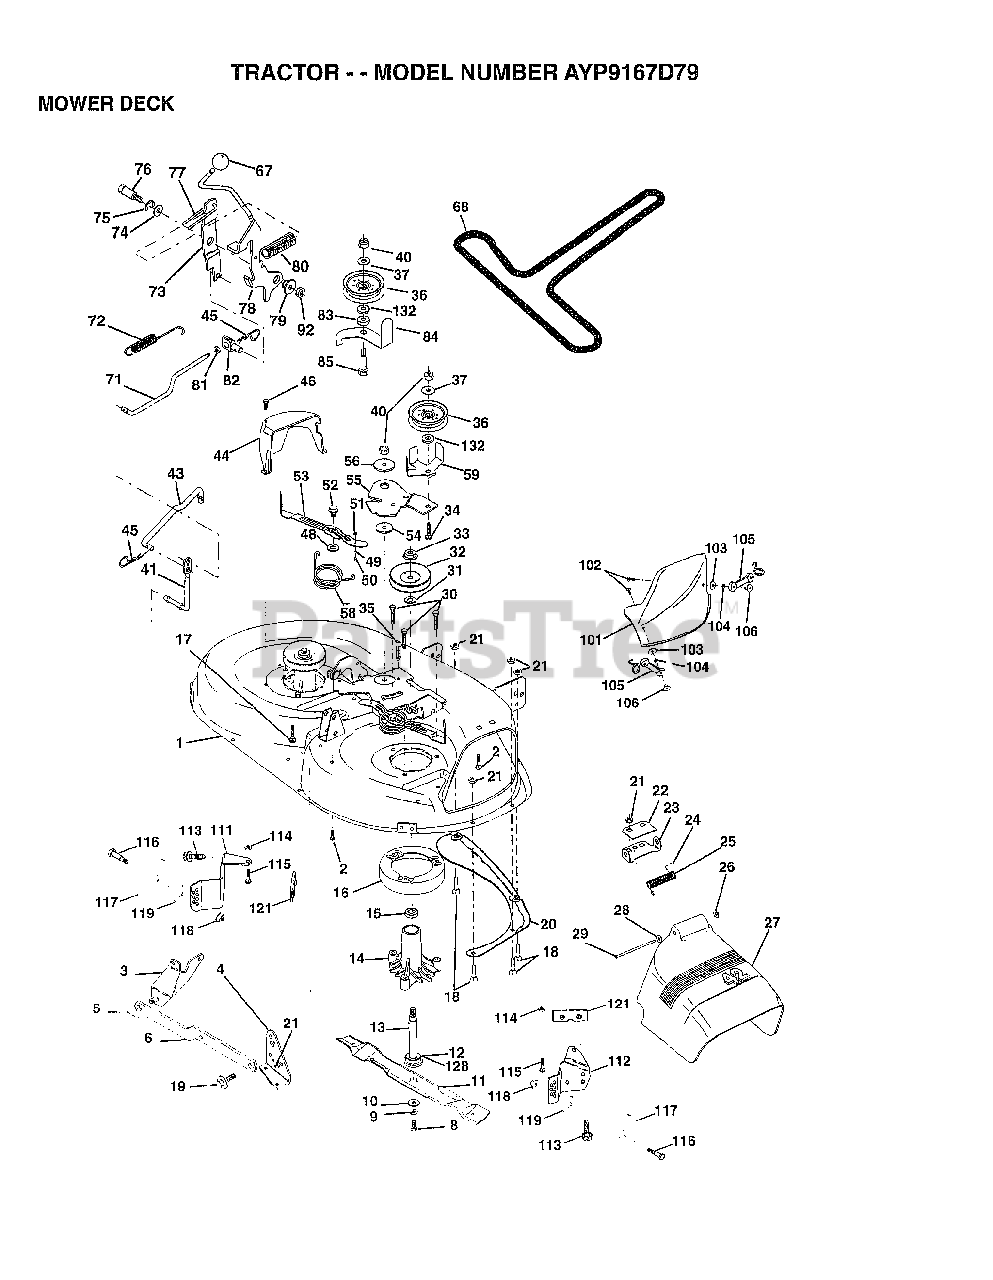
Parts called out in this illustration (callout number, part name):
1	DECK.WELD.42.
2	BOLT
3	BRKT ASM SWAY BAR
4	BRKT DECK SW BAR
8	BLADE BOLT
10	WASHER.HARD.BLADE
11	"BLADE.42"" MULCHER"
12	BEARING.BALL
14	HSG ASM MANDREL
15	BEARING
16	STRIPPER RND MWR
17	BOLT RDHD 3/8-16
18	BOLT
19	BOLT SHD 5/16-18
22	STIFFENER BRKT
23	DEFLECTOR BRKT
24	CAP-SLEEVE LT
25	SPRING TORSION
27	DEFLECTOR.SHIELD
28	WASHER
29	HINGE ROD
30	"SCREW-THD ROLL,WA"
31	WASHER
32	PULLEY.MANDREL.42
34	BOLT
35	XMAS TREE FASTNER
36	FLAT IDLER PULLEY
37	WASHER
41	PIVOT ROD
43	ROD CLUTCH W/NIBS
44	GUARD MAND LH BLK
46	SCREW.1/4-20X5/8
48	HARD SMALL WASHER
49	ROLLER ASM-CAM
50	SHOULDER BOLT
51	LOCKNUT
52	BOLT.SHLD.5/16-18
54	HARDENED WASHER
55	ARM-IDLER
56	SPACER RETAINER
58	SPRING TORSN BRAK
59	GUARD IDLER TUV
67	KNOB T(3/8 HOLE)
68	BELT.V.T-PATH
71	ROD CLUTCH 38/42
72	RETURN SPRING
73	CLUTCH ARM SECOND
74	WASHER
75	RING
76	SHOULDER BOLT
77	SPRING KEEPER
78	LEVER ASM-CLUTCH
79	BUSHING
80	SPRING.CLUTCH.MWR
81	TRUNION ADJ
82	NUT
83	WASHER
84	"KEEPER-BELT,FIXED"
85	BOLT RDHD 3/8-16
92	NUT
101	"COVER.MULCH.42"""
102	SCREW
103	WASHER #10
104	LOCKWASHER
105	LATCH ASSY.BAGGER
106	WELDNUT
111	BRACKET.GWHL.LH.
112	BRACKET.GWHL.RH.
113	SCREW
116	BOLT.SHOULDER
117	WHEEL GAGE DONUT
118	LOCKNUT
119	WASHER
121	BRACKET.EXTRD.GWL
128	WASHER.FELT.
132	WASHER GT
